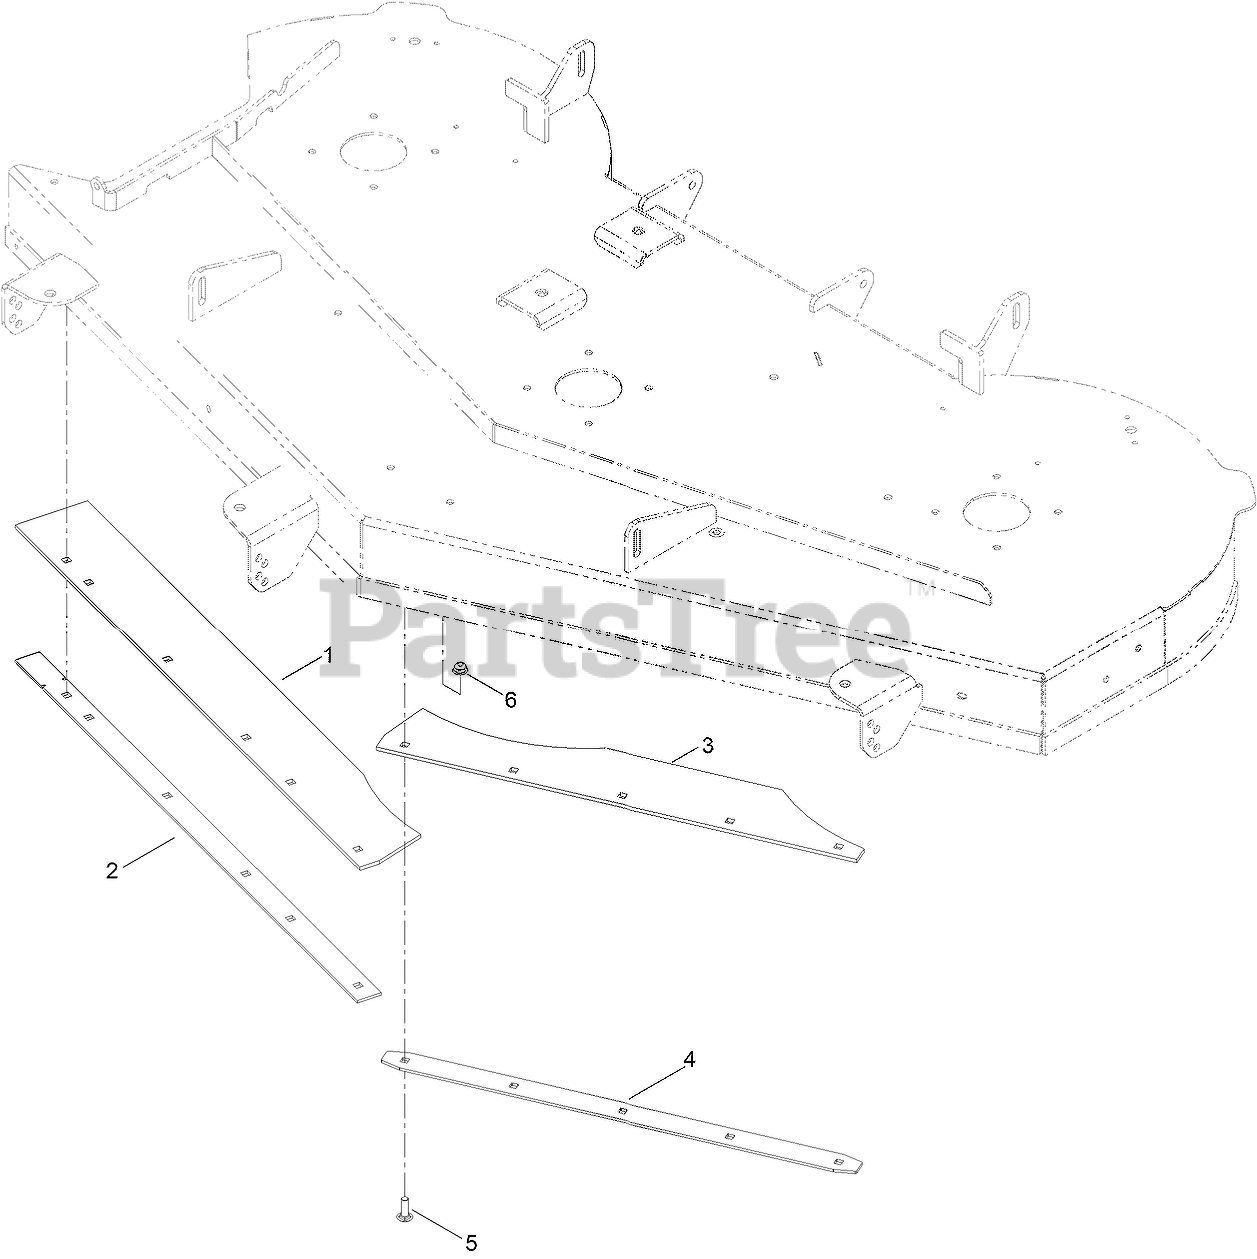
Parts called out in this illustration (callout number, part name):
1	SKIRT-RUBBER, FRONT
2	SKID-SKIRT
3	SKIRT-RUBBER, FRONT
4	PLATE-SKIRT
5	SCREW-CARR
6	NUT-HF
